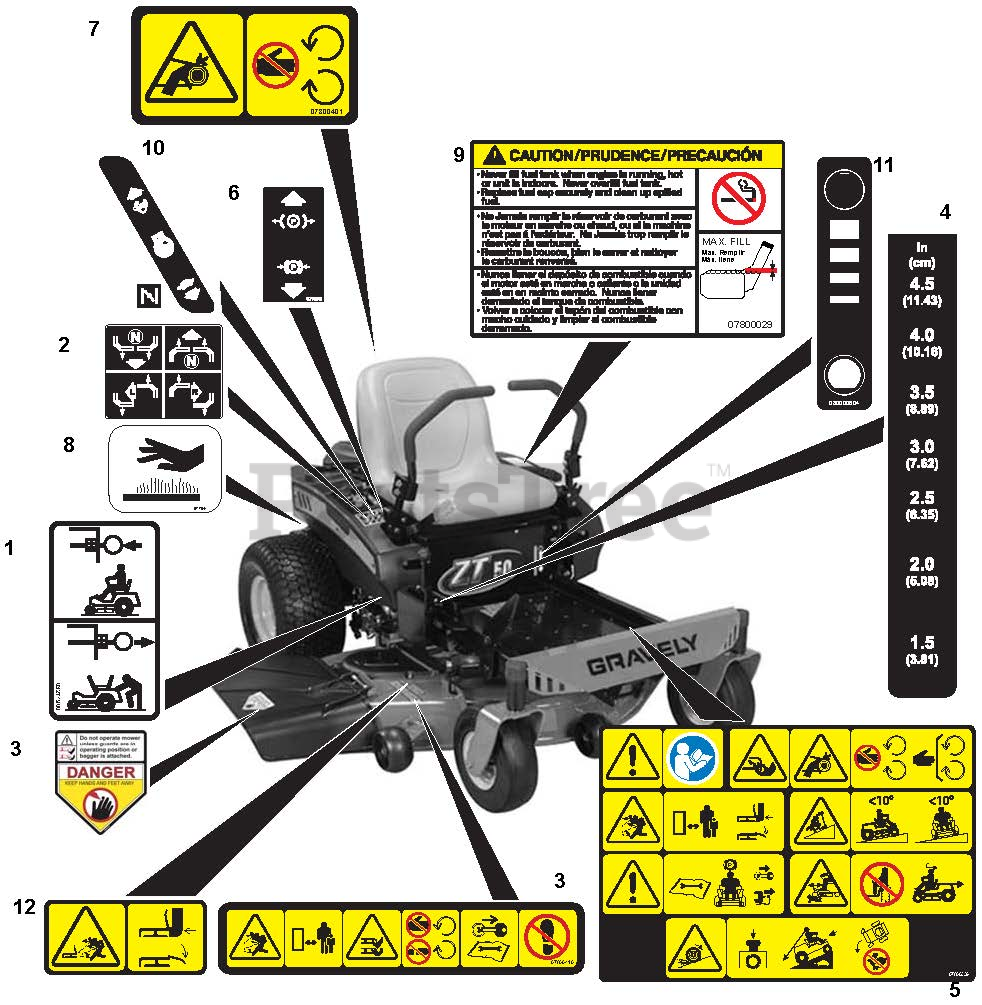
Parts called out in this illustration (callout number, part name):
1	Decal, Transmission Disconnect
2	Decal, Instructional Steering
3	Decal, Safety – Mower Deck
4	Decal, Cut Height
5	Decal, Safety – Main
6	Decal, Parking Brake Lever
7	Decal, Safety – Guarding
8	Decal, Hot Surface
9	Decal, Fuel Warning
10	Decal, Throttle Control
11	Decal, Fuel Level
12	Decal, Safety – Deck Guarding
